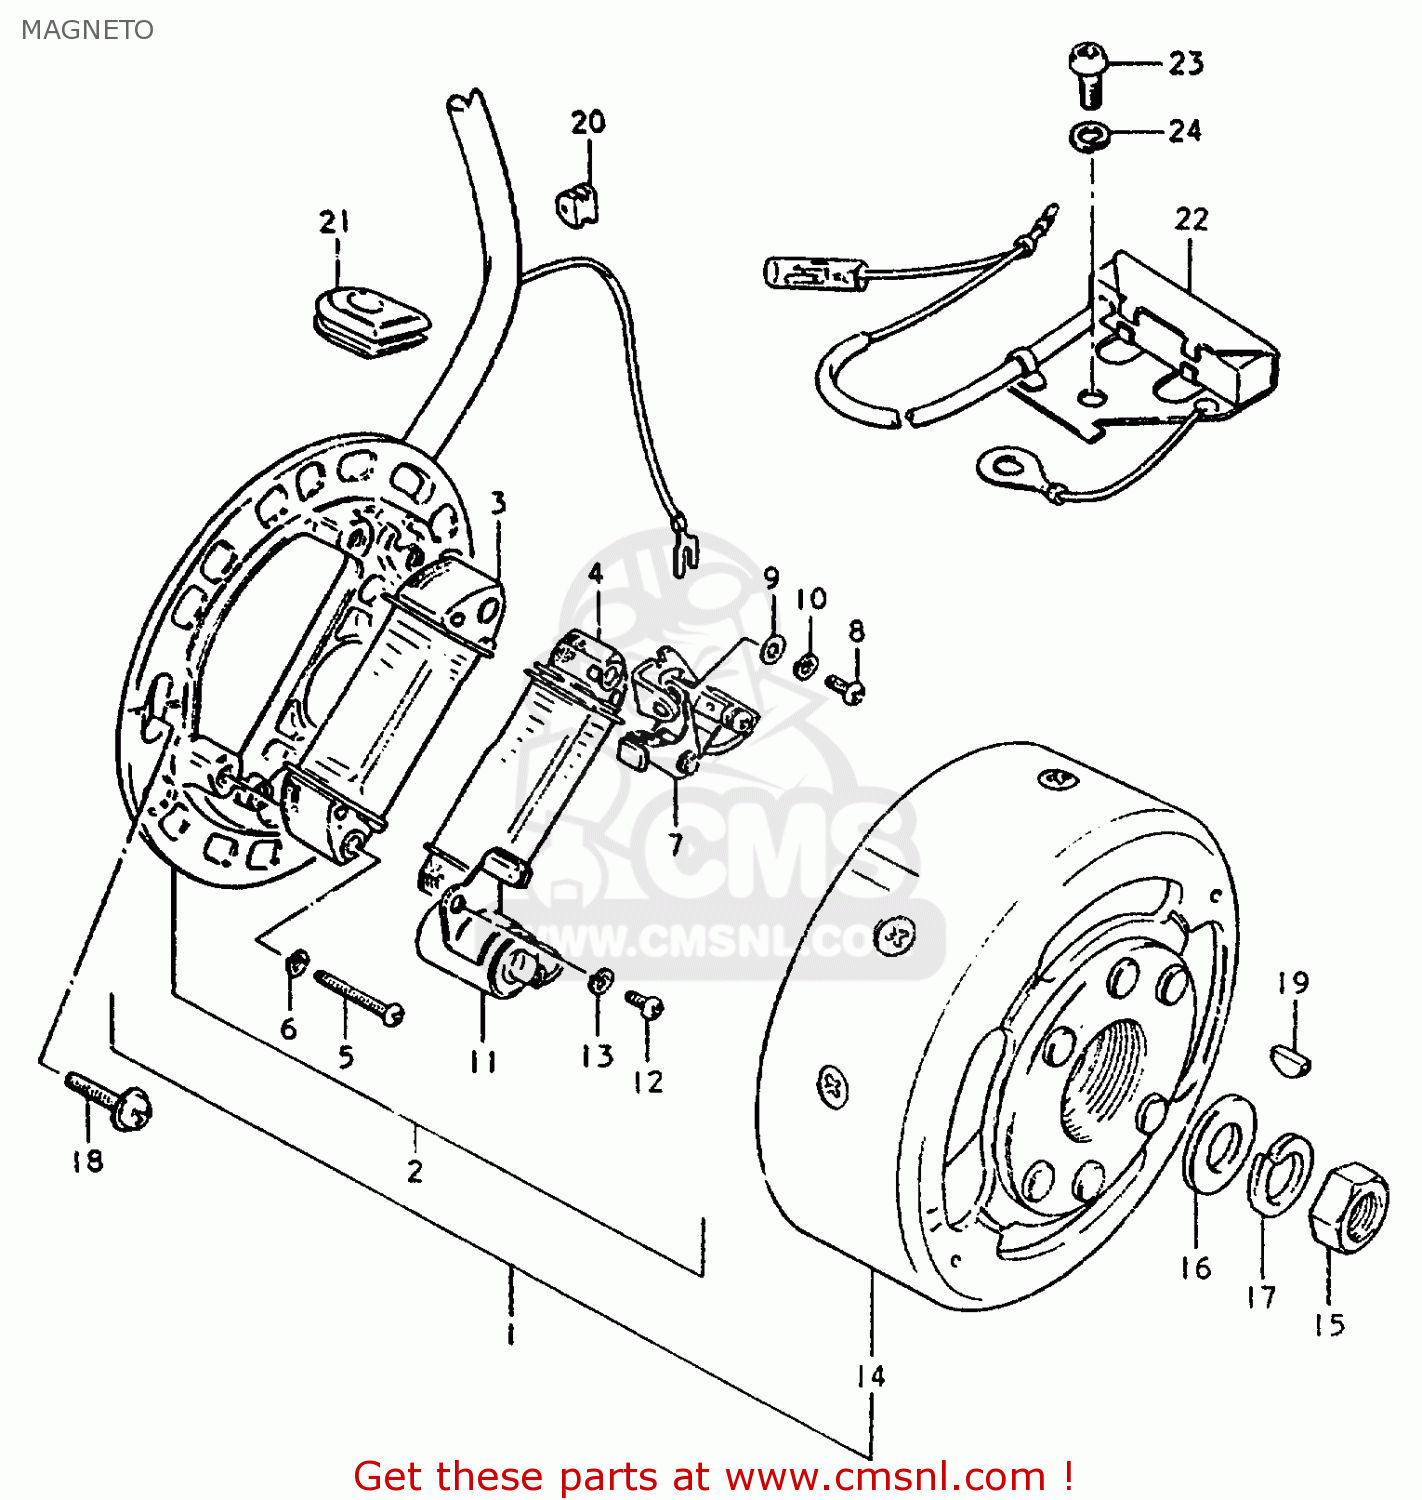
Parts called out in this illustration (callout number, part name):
1	MAGNETO ASSY
2	STATOR ASSY
3	COIL, LIGHTING
4	COIL,PRIMARY
5	SCREW (4X30)
6	LOCK WASHER
7	POINT ASSY,CONTACT
8	SCREW(4X10)
9	WASHER
10	LOCK WASHER
11	CONDENSER
12	SCREW
13	LOCK WASHER
14	ROTOR ASSY
15	NUT (10MM)
16	WASHER
17	LOCK WASHER
18	SCREW(5X14)
19	KEY
20	GROMMET,NEUTRAL LEAD WIRE
21	GROMMET
22	RESISTOR ASSY
23	SCREW
24	LOCK WASHER
